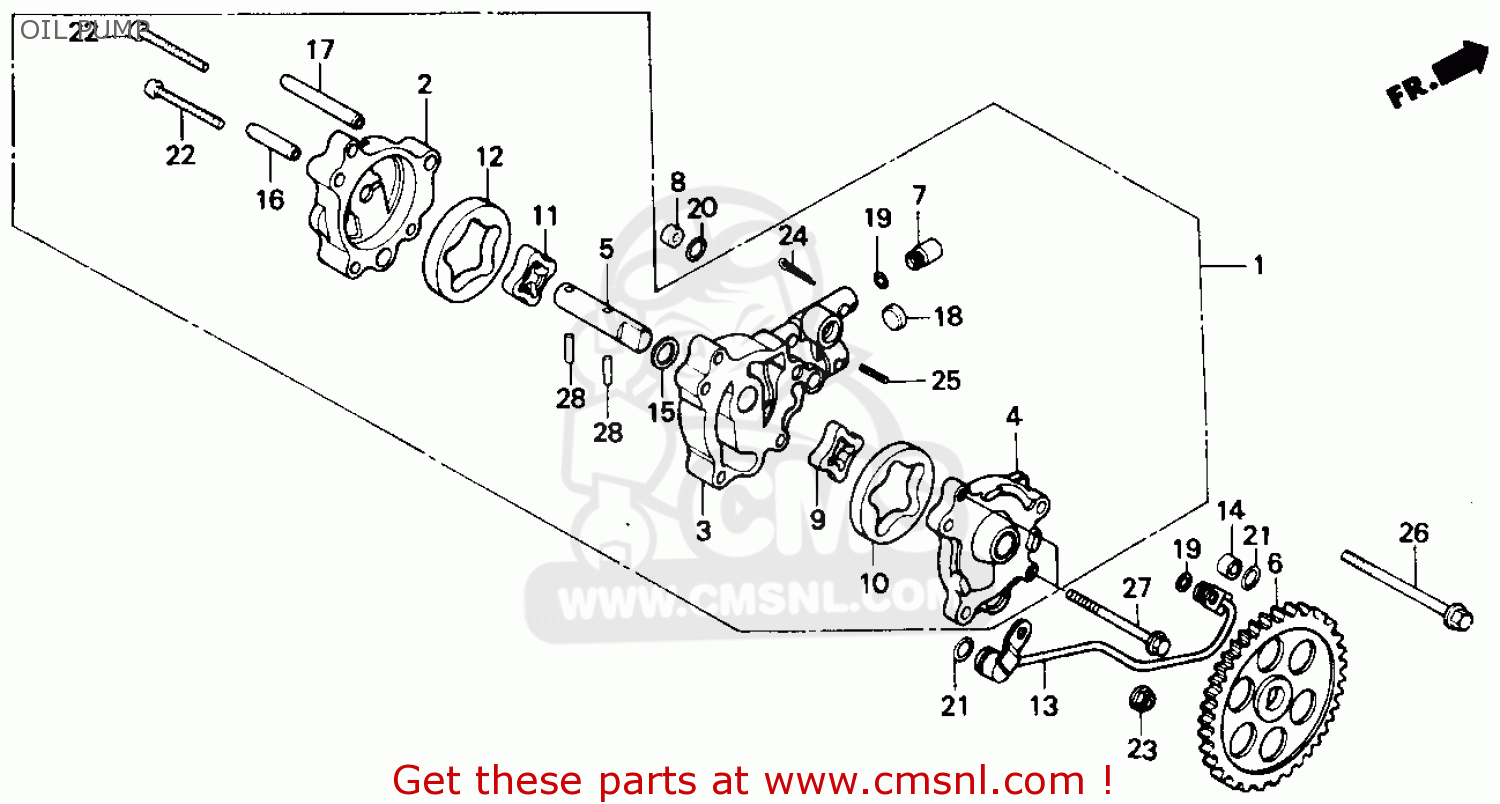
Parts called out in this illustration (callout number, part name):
1	PUMP ASSY.,OIL
2	BASE,OIL PUMP
3	SPACER,OIL PUMP
4	BODY,OIL PUMP
5	SHAFT,OIL PUMP
6	GEAR,OIL PUMP DRI
7	STOPPER,OIL LEAK
8	ORIFICE,5.5MM
9	ROTOR A,PUMP IN
10	ROTOR A,PUMP OUT.
11	ROTOR B,PUMP IN.
12	ROTOR B,PUMP OUT.
13	PIPE COMP.,OIL
14	COLLAR,HOLDER
15	WASHER,THRUST
16	PINDOWEL,8X24
17	PINDOWEL,8X44
18	PLUG,SEALING,11MM
19	O-RING,7X1.7
20	O-RING
21	O-RING,1.5X9.5
22	SCREW,PAN,5X40
23	NUT,FLANGE,6MM
24	PIN,SPLIT,3
25	PIN,SPRING,2.5X18
26	BOLT,FLANGE,6X50
27	BOLT,FLANGE,6X60
28	ROLLER,4X15.8
